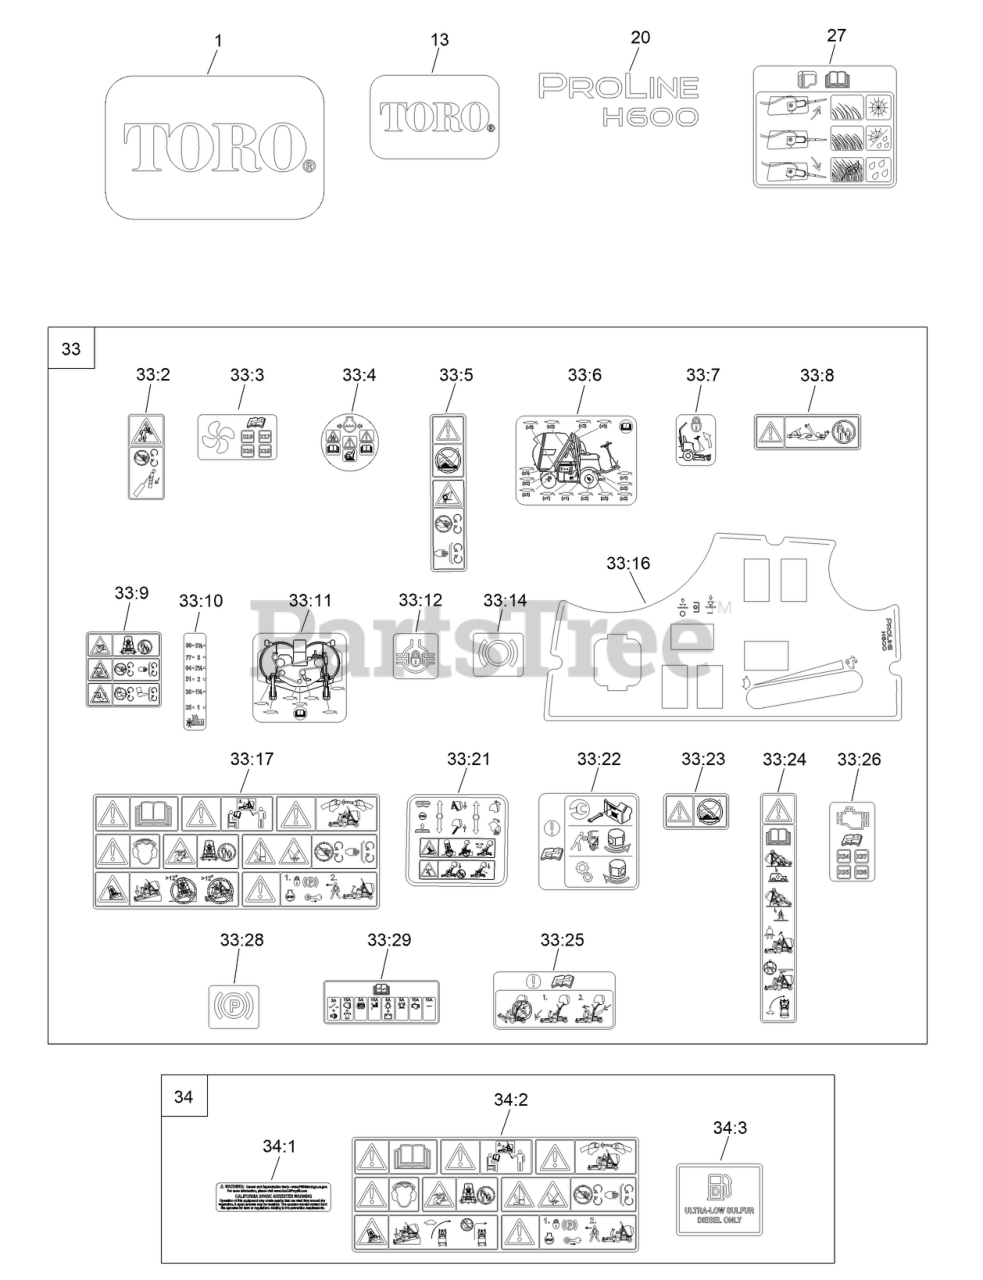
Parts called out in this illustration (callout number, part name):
13	DECAL-LOGO, TORO
20	DECAL-PROLINE H600
27	DECAL-HOPPER SENSOR
33	Proline H600 DECAL SET
33:2	DECAL-WARNING ARM
33:3	DECAL-RELAY FAN
33:4	DECAL-DANGER
33:5	DECAL-WARNING ENGINE
33:6	DECAL-SERVICE
33:7	DECAL-FOOTPLATE TILT
33:8	DECAL-CARDAN JOINT
33:9	DECAL-WARNING DECK
33:10	DECAL-HOC
33:11	DECAL-SERVICE
33:12	DECAL-DIFFERENTIAL LOCK
33:14	DECAL-BRAKE
33:16	DECAL-CONTROL PANEL
33:17	DECAL-WARNING
33:21	DECAL-CONTROLS SAFETY
33:22	DECAL-HYDROSTATIC PUMP BYPASS
33:23	DECAL-HOT SURFACE
33:24	DECAL-ROPS WARNING
33:25	DECAL-ATTENTION, DECK SERVICE
33:26	DECAL-ENGINE RELAY
33:28	DECAL-PARKING BRAKE
33:29	DECAL-FUSE
34	ANSI DECAL KIT
34:1	DECAL-ARRESTOR, SPARK
34:2	DECAL-WARNING
34:3	DECAL-DIESEL, ULTRA-LOW
